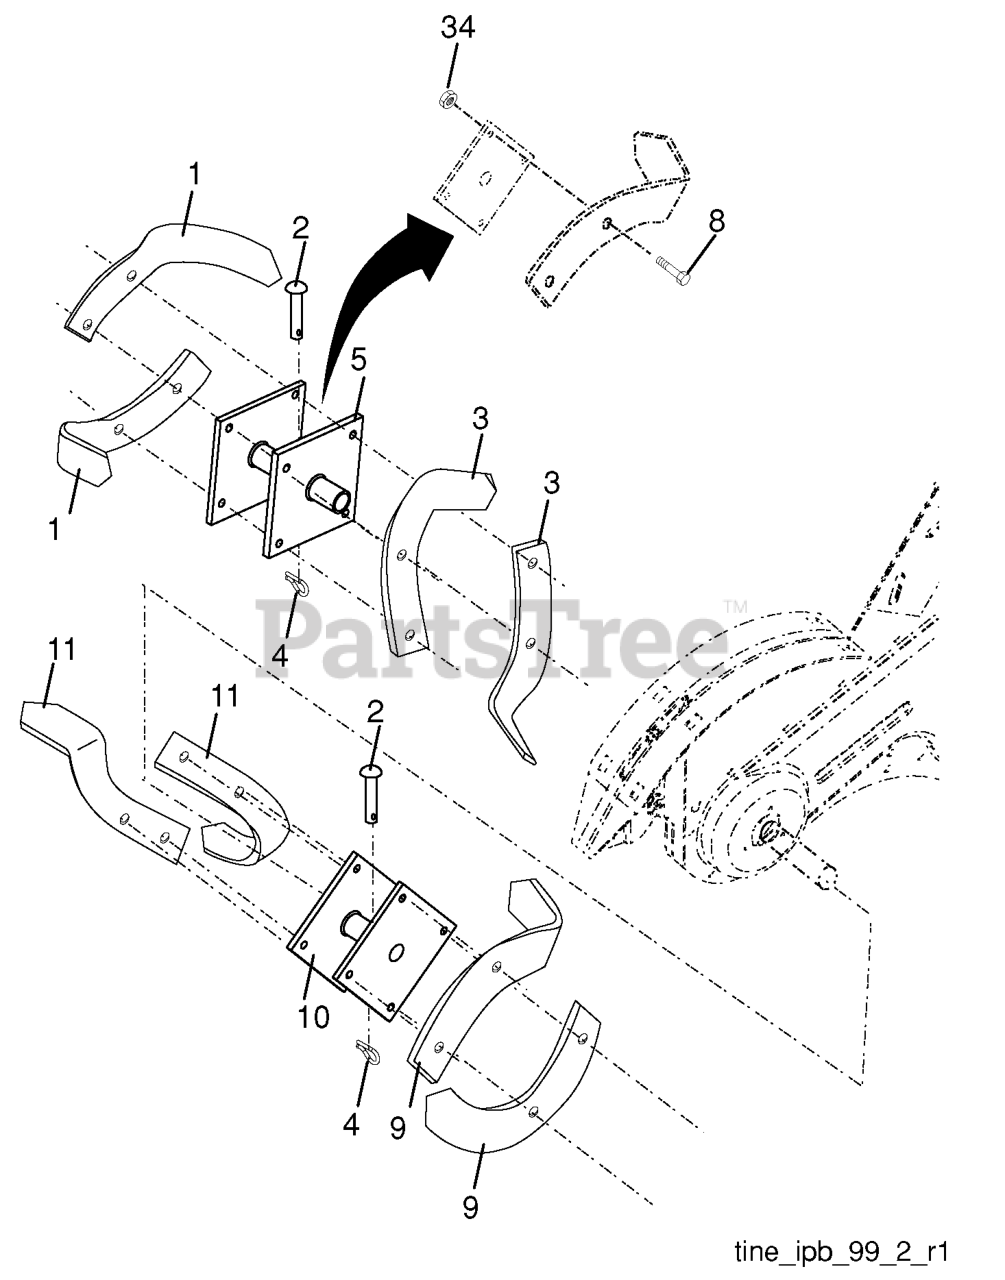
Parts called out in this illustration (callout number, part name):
1	TINE TI
2	PIN RETAINING SCREW
3	TINE.LH.12"(72L)
4	SPRING RETAINER
5	HUB.&.PLATE.LH.TILLER.BLACK
8	BOLT.HEX.001X20.37-24X1.ZINC
9	TINE TI
10	HUB.ASM.RH.14".BLACK.TILLER
11	TINE.RH.12"(72R)
34	NUT CROWNLOCK 3/8-24
